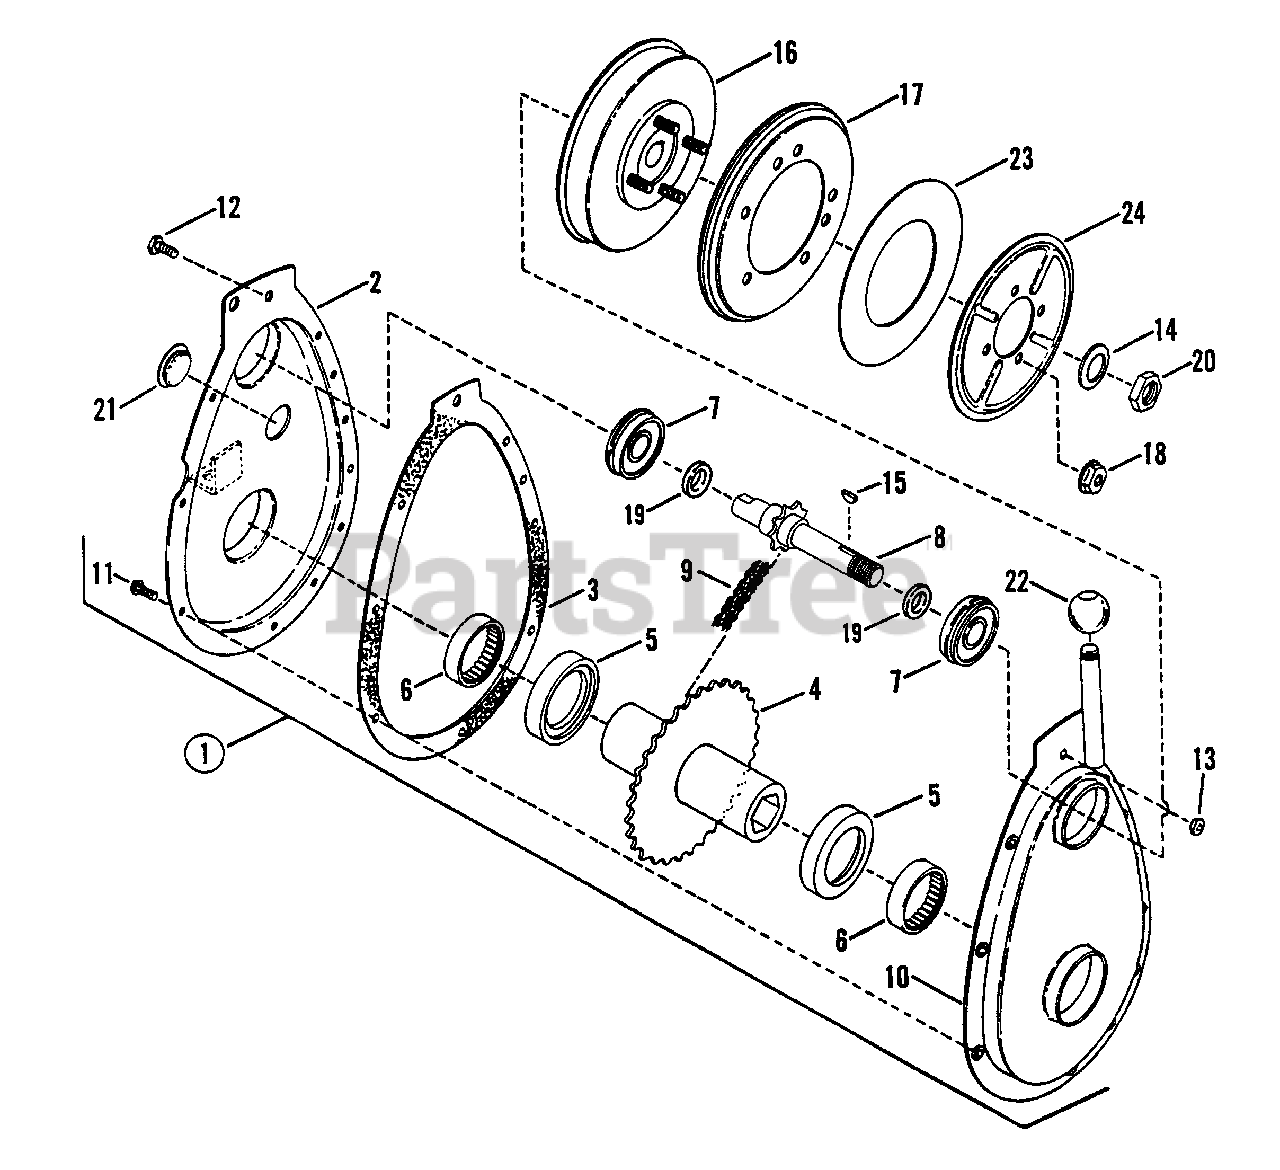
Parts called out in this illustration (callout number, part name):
1	ASSEMBLY, Primary Chain Case
2	COVER, Case
3	GASKET, Case/Cover
4	HUB & SPROCKET
5	THRUST-WASHER
6	BEARING, Needle
7	BEARING, Ball
8	SHAFT, Input
9	CHAIN, 46 Pitch (#35 Endless)
10	CASE, Sprocket
11	SCREW, #10-24 x 1/2" Hex Washer Self-Tap (Torx)
12	SCREW, 1/4-20 x 5/8" Hex Head Cap, Gr. 5
13	NUT, 1/4-20 Hex Center Lock
14	WASHER, 5/8" Belleville
15	KEY, 1/8 x 5/8 Woodruff
16	HUB, Driven Disc
17	DISC, Driven
18	NUT, 5/16-18 Hex Flange Lock, Grade 5
19	O-RING, 5/8
20	NUT, 5/8-18 Hex Center Lock
21	PLUG (Oil fill & check)
22	BUSHING, Primary Clutch Ball
23	WASHER, Thrust
24	PLATE
